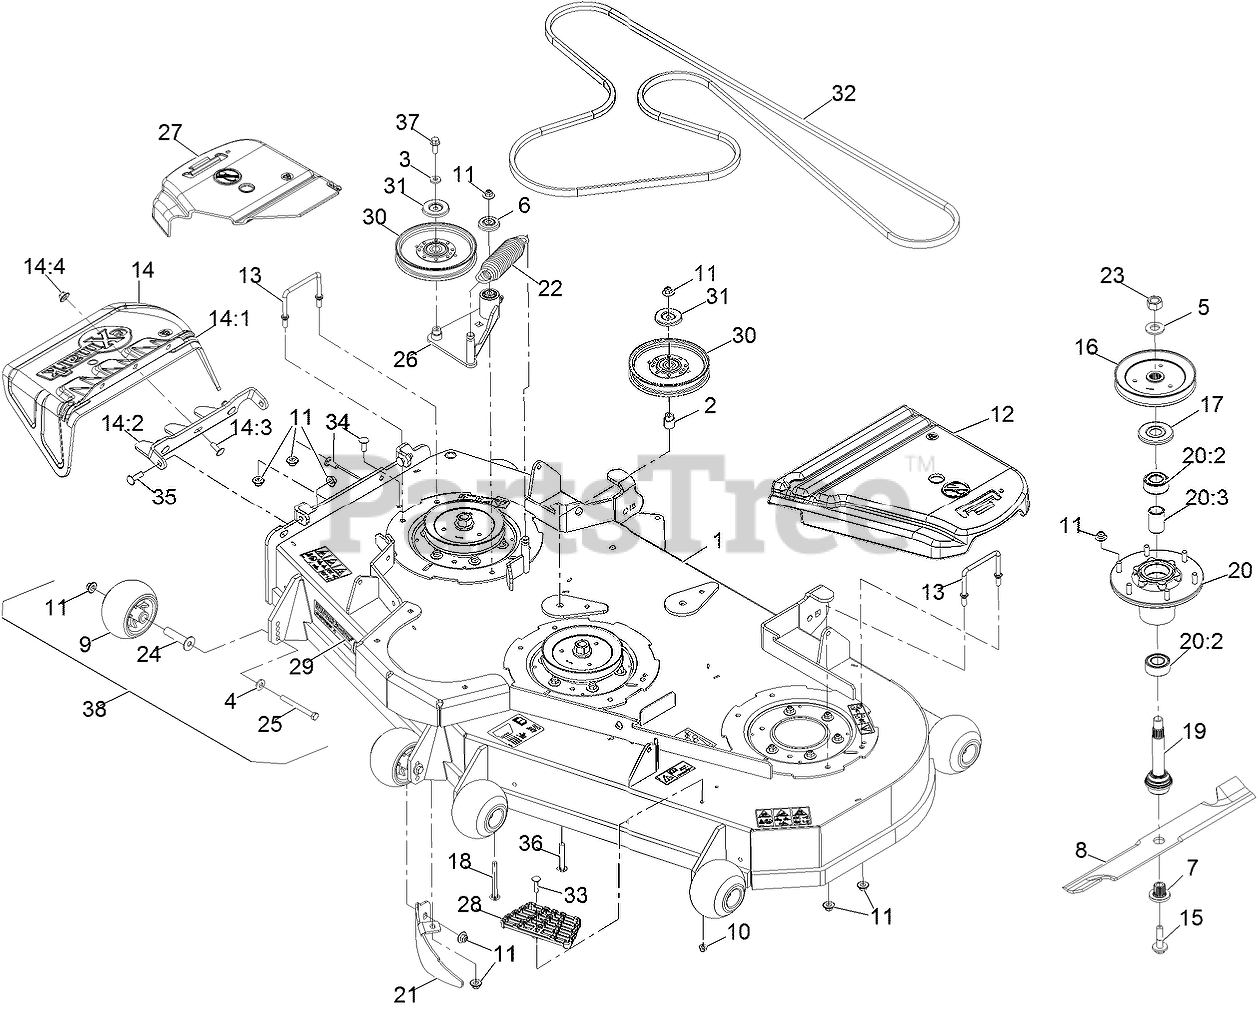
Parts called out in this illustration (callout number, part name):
1	ASM-DECK COMPLETE 603
2	BUSHING-IDLER
4	WASHER-BELLEVILLE
6	GUARD-TOP
7	BUSHING,SPLINED
8	Blade-Extreme 2, 20.50"
9	ROLLER-SCALP, ANTI
10	NUT-HF, NI
11	Nut-Nyloc 3/8-16 Flg
12	COVER-BELT, LH
13	WIREFORM-COVER
14	ASM,DISCHARGE CHUTE
14:1	CHUTE,DISCHARGE
14:2	BRACKET,DISCHARGE CHUTE
14:3	SCREW-CARR
14:4	Nut-Nyloc 3/8-16 Flg
15	SCREW,SEMS 1/2-20 X 2.19
16	SHEAVE,BLADE DRIVE 6.50
17	GUARD-BEARING, TOP
18	BOLT-SHOULDER, CARRIAGE 3/8-16 X 3 1/2
19	ASM-SPINDLE AND SEAL
20	ASM-CUTTER HSG
20:2	BEARING-3205 TRASHGUARD
20:3	SPACER-BEARING
21	DOGLEG - LZ60
22	SPRING-EXTENSION
23	NUT-HEX
24	AXLE, ROLLER
25	SCREW-HH 3/8-16 X 3 3/4 GR 8
26	IDLER ARM ASM
27	BELTSHIELD-RT, 60
28	STEP-DECK
29	DECAL, 604
30	IDLER-PULLEY
31	SHIELD-DUST
33	Bolt-Carriage 5/16-18 X 1 1/4
34	SCREW-CARR
35	Bolt-Carriage 3/8-16 X 1 1/4
36	SCREW-CARR
37	SCREW-HHF
38	KIT, ANTI-SCALP ROLLER
